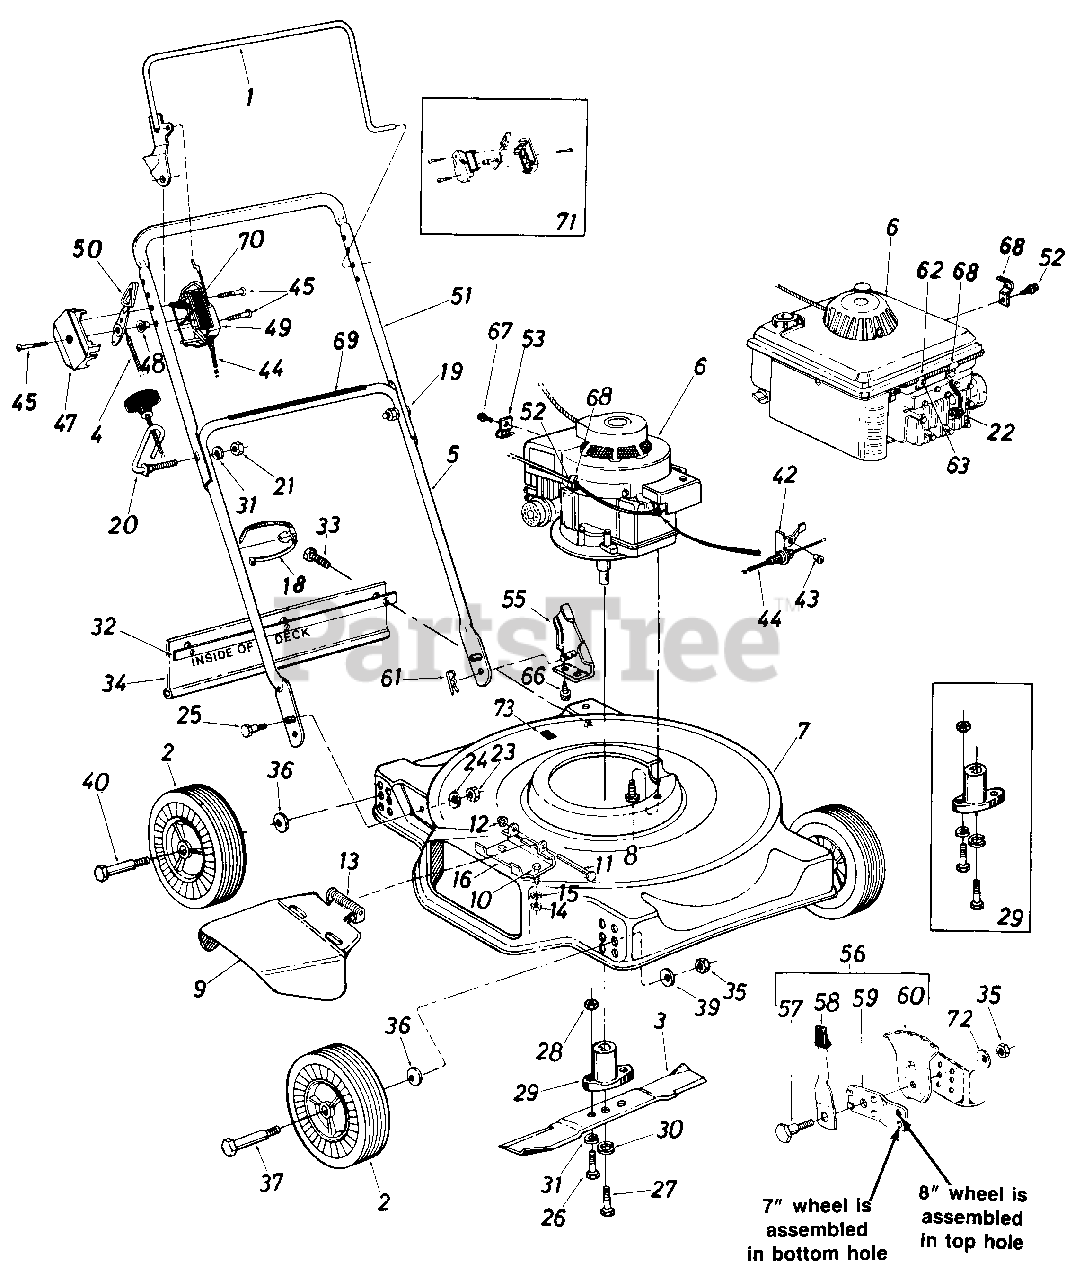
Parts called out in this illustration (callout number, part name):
1	Control Handle Ass'y.-R.H.
2	Wheel Ass'y. Comp.
4	Throttle Control Wire-39"
5	Lower Handle
6	Engine
9	Chute Deflector Ass'y.
10	Hex Bolt 1/4-20 x .50" Lg.
11	Hinge Pin 1/4" Dia. x 3.88 Lg.
12	Push Cap .25" Rod
13	Torsion Spring
14	Hex Nut 1/4-20 Thd.
15	L-Wash. 1/4" I.D.
16	Deflector Hinge Plate
18	Cable Tie
19	Curved Carriage Bolt 5/16-18 x 1.38" Lg.
20	Rope Guide Bolt
21	Hex Nut 5/16-18 Thd.
26	Hex Bolt 5/16-24 x 1.00" Lg. (Grade 5) Special
27	Hex Bolt 3/8-24 x 2.25n Lg. (Grade 5)
28	Hex Nut 5/16-24 Thd.
29	Blade Adapter Kit
30	L-Wash. 3/8" I.D.-H.D.
31	L-Wash. 5/16n l.D.
32	Retainer Strip
33	Hex Wash. Hd. AB-Tap Scr. 1/4 " X .62n Lg.
34	Rear Flap Ass'y.
35	Hex Nut 3/8-16 Thd.
36	Bell-Wash. .400" I.D. x .88"
37	Front Axle Bolt
40	Rear Axle Bolt
42	Cable Bracket
44	49" Control Cable-Blue
45	Truss Mach. Scr. #12 x 1.50"
47	Control Panel Half
48	Control Disc Pin
49	Clutch Panel Half
50	Throttle Control Lever
51	Upper Handle
52	Hex "B" Tap Scr. #10 x .38"
53	Casing Clamp
55	Handle Mount Brkt. Ass'y.-L.H.
56	Height Adjuster Ass'y. Comp.-R.H.
57	Shoulder Bolt .500" Dia. x .357
58	Spring Lever Ass'y. w/Knob
59	Pivot Bar
60	Index Plate
61	Hairpin Cotter
63	Hex Self-Tap Scr. #8 x .62"
66	Hex Wash. Hd. Self-Tap Scr. 5/16-18 x .50" Lg.
67	Hex Wash. Hd. AB-Tap Scr. #8 x .38" Lg.
68	Cable Clip
69	Instruction Label-Handle
70	Control Label-Throttle
71	Kit-Control Housing Comp.
72	Belleville Wash. .39 I.D. x 1.4 O.D.
73	Plastic Plug
8072-000-7	Hardware Pack
